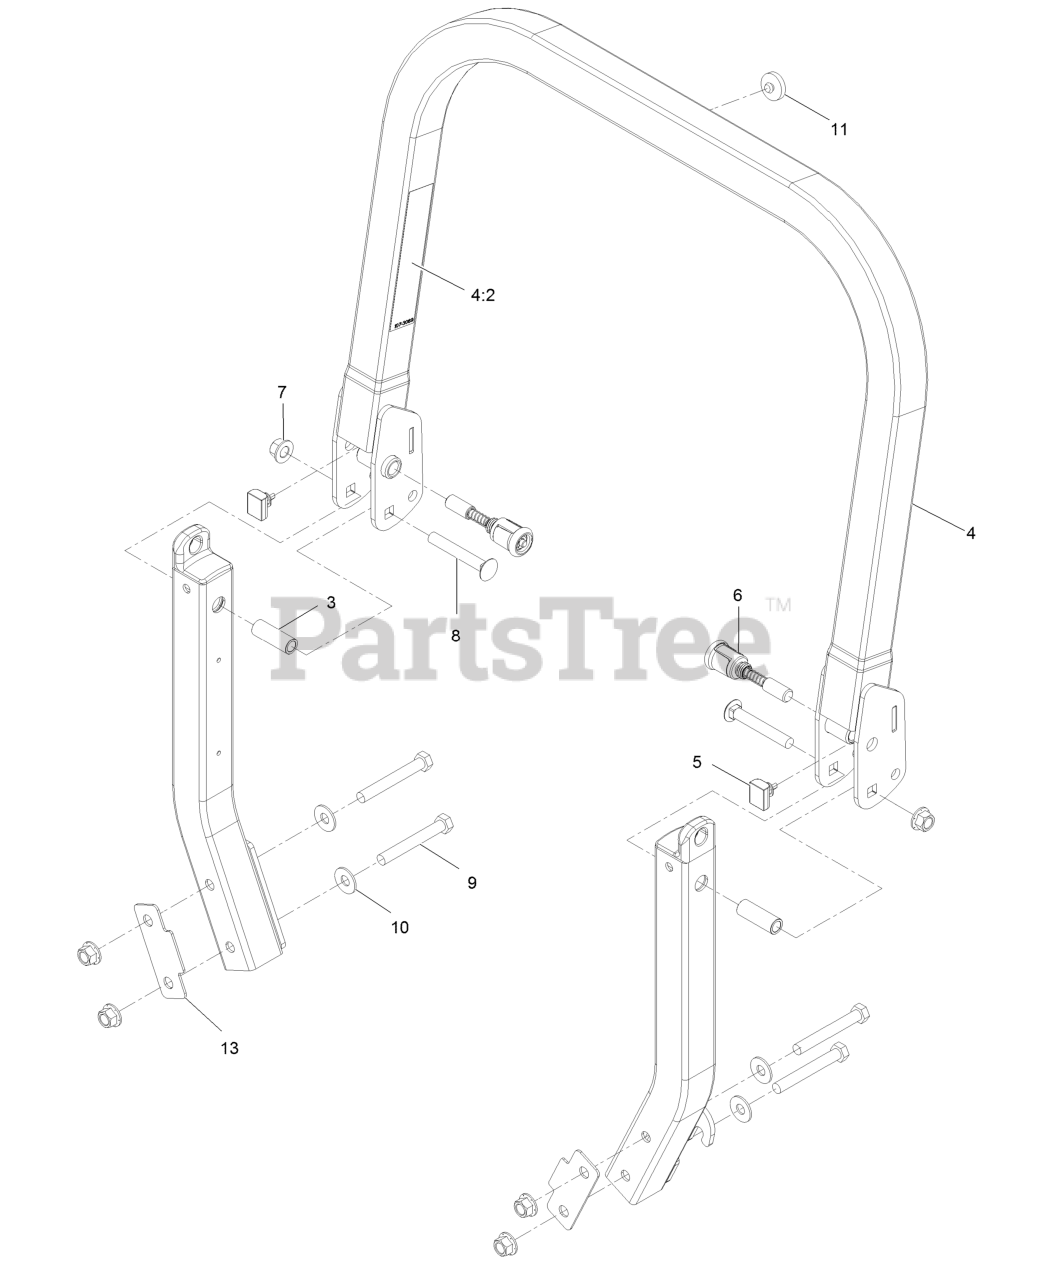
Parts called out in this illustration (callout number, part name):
4	Upper ROPS ASM
4:2	Decal-Warning
5	Bumper-ROPS
6	Pin-Spring
7	Nut-Lock 1/2-13
8	Bolt-Carriage 1/2-13 X 3 1/2
9	Screw-HH
10	Washer, Spring Disc 1/2
11	Bumper-Push-In, Rubber
